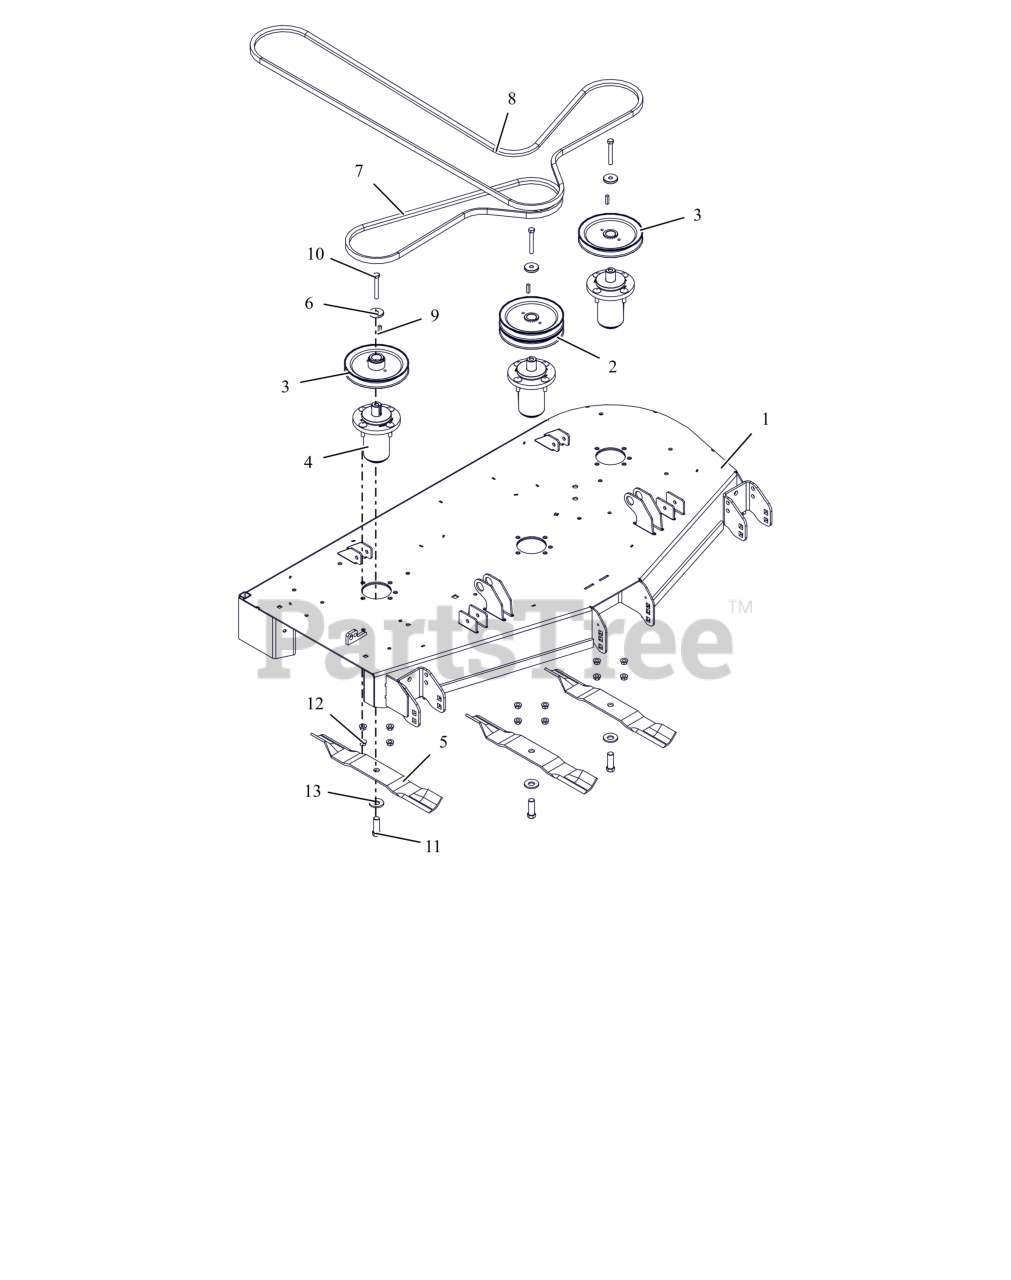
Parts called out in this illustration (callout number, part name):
1	KIT,DECK-52" W/DECALS-GRAVELY
2	PULLEY, DOUBLE-1"ID X 6.75"OD
3	PULLEY, V-1" ID X 6.75" OD
4	ASM, MAINT FREE ALUM SPINDLE
5	BLADE, 18"
6	RETAINER, SHEAVE
7	V-BELT, B-COGGED
8	V-BELT, HB SECTION
9	KEY, SQ .25X.25X1.00 RC 40-50
10	BLT, HEX .38-16X2.75 G8 ZCC
11	BLT, HEX .62-18X1.75 G8 ZCC
12	NUT-LK-CTR-FLG .375-16 GF ZCC
13	WSHR-BLVL .669X1.535X.138
